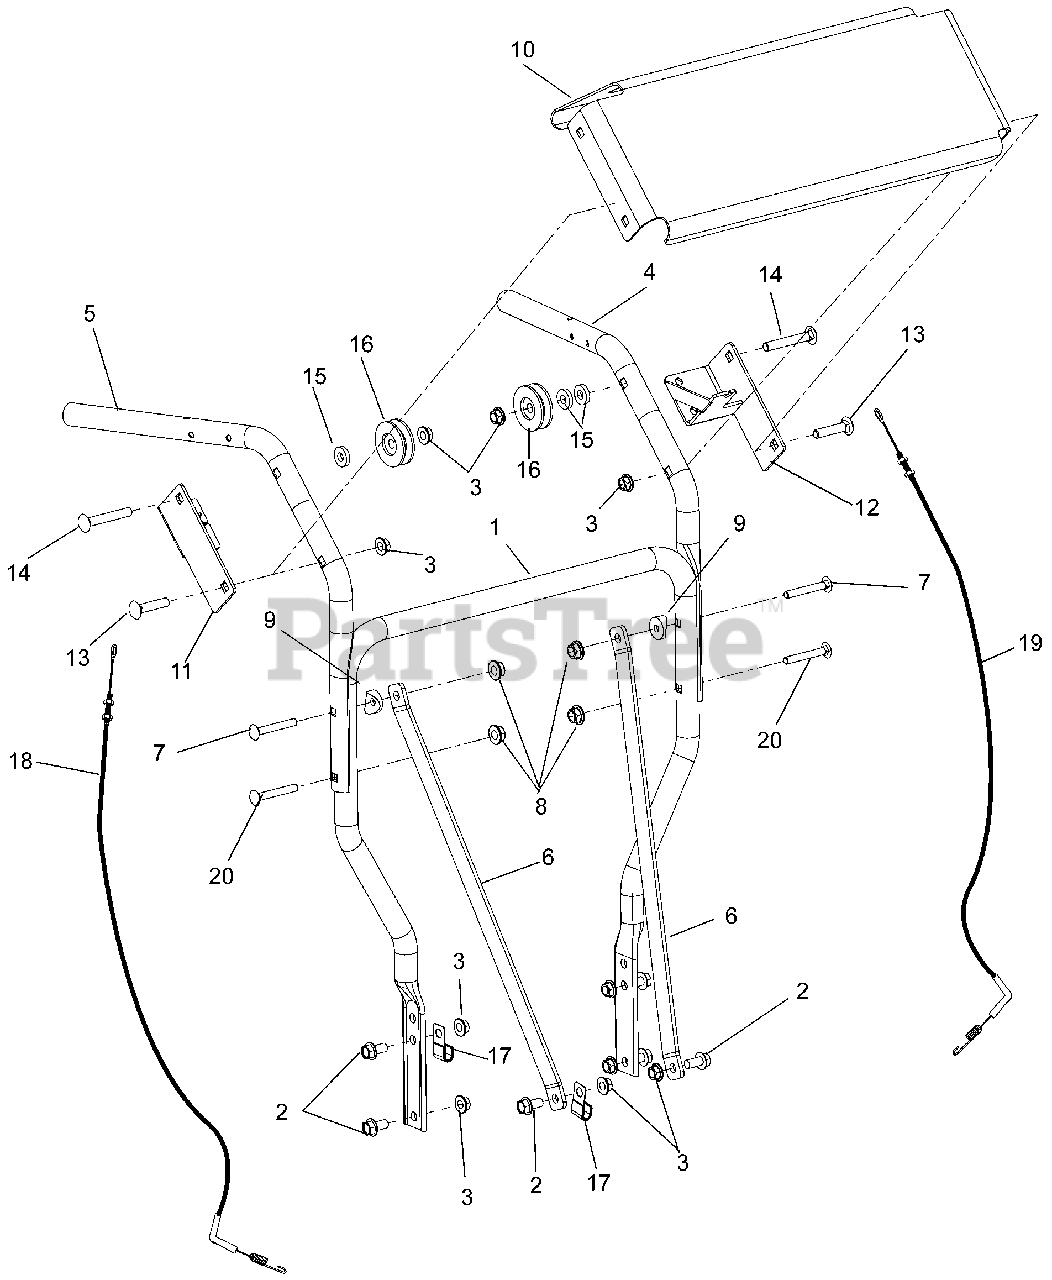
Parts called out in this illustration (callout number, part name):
1	Handlebar, Lower
2	Bolt, Screw Hex Flanged Whiz Lock Head .38-16 x .75
3	Nut, Locking Top Flange .38-16
4	Handlebar, Upper Left Hand
5	Handlebar, Upper Right Hand
6	Bracket, Handlebar Brace
7	Bolt, Round Head Square Neck .31-18 x 2.25
8	Nut, Nyloc Flange .31-18
9	Spacer, Handlebar
11	Mount, Brake Cable Pillow
12	Mount, PTO Cable
13	Bolt, Round Head Square Neck .38-16 x 1.75
14	Bolt, Round Head Square Neck .38-16 x 2.50
15	Washer, Flat Steel .390 x .88 x .18
16	Idle, 3L Front Side .38 x 1.875
18	Cable, Brake Control
19	Cable, PTO Control
20	Bolt, Round Head Square Neck .312-18 x 1.75
